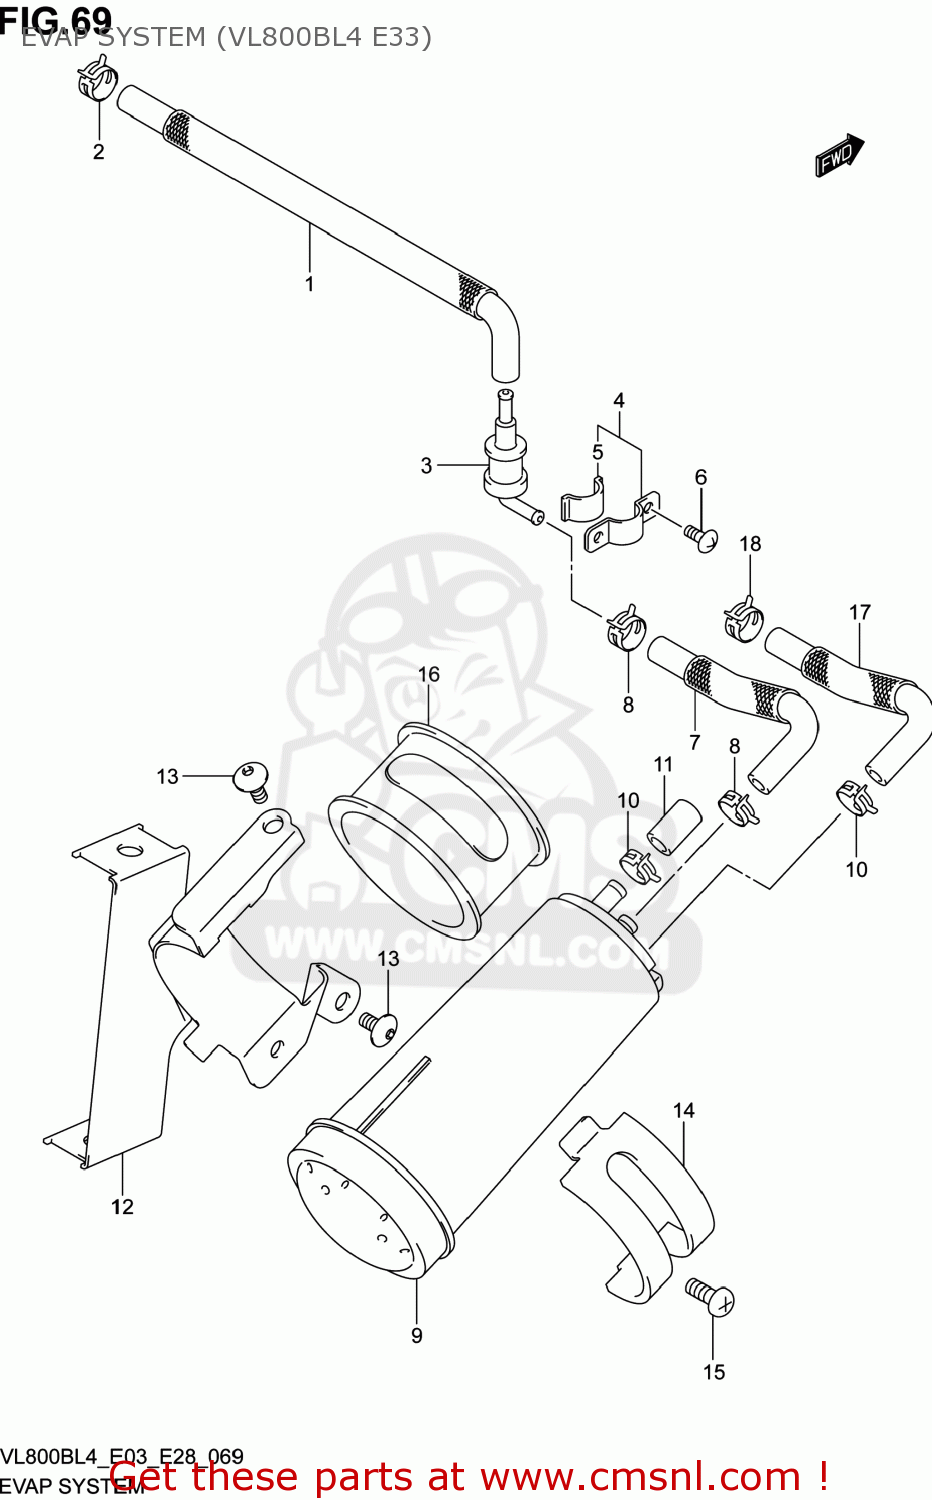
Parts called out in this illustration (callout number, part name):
1	HOSE,TANK & BREATHER VALVE
2	CLIP
3	VALVE,FUEL TANK BREATHER
4	PLATE,FUEL TANK BREATHER NO.2
5	CUSHION
6	SCREW
7	HOSE,BREATHER VALVE & CANISTER
8	CLIP
9	CANISTER SET
10	CLIP
11	CAP,OD:11.5
12	BRACKET,FI CONTROL UNIT
13	SCREW(6X12)
14	HOLDER,CANISTER
15	SCREW
16	CUSHION,CANISTER
17	HOSE,CSTR PURGE
18	CLIP
